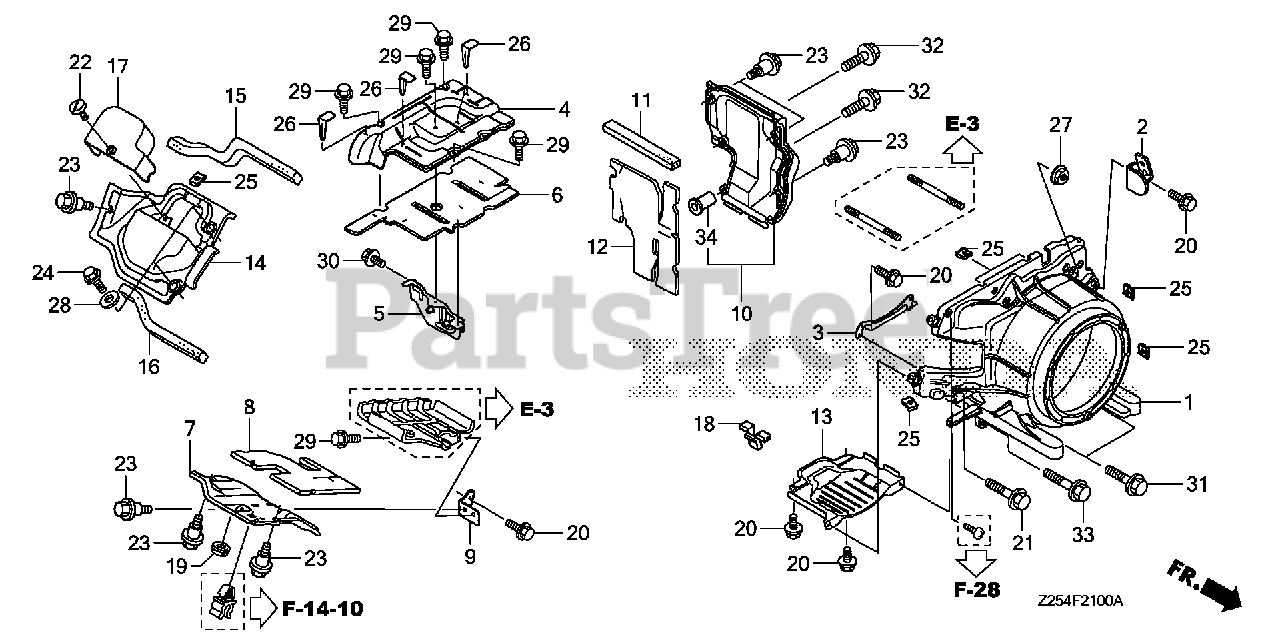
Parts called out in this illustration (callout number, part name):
1	COVER, FAN
2	PLATE, R. SIDE
3	BRACKET, FAN COVER
4	SHROUD (UPPER)
5	BRACKET, SHROUD (UPPER)
6	INSULATOR, SHROUD (UPPER)
7	SHROUD (LOWER)
8	INSULATOR, SHROUD (LOWER)
9	BRACKET, SHROUD (LOWER)
10	SHROUD, R. SIDE
11	SEAL, R. SIDE COVER
12	INSULATOR, R. SIDE COVER
13	SHROUD (LOWER)
14	SHROUD, HEAD COVER
15	SEAL, HEAD COVER SHROUD (UPPER)
16	SEAL, HEAD COVER SHROUD (LOWER)
17	COVER, PLUG
18	RUBBER, OIL CHECK
19	GROMMET, SPEAKER PANEL
20	BOLT, FLANGE (6X12) (CT200)
21	BOLT, FLANGE (6X23)
22	BOLT, AIR CLEANER COVER (- SCREW)
22	SCREW, SPECIAL (6X16)
23	BOLT, SPECIAL (6MM)
24	BOLT, FLANGE (6X12) (CT200)
25	NUT, SPRING (6MM)
26	CLIP, INSULATOR BIND (A)
27	NUT, FLANGE (6MM)
28	WASHER, PLAIN (6MM)
29	BOLT, FLANGE (6X12) Use up to Engine SN 1543277.
30	BOLT, FLANGE (6X12)
31	BOLT, FLANGE (6X20)
32	BOLT, FLANGE (6X22)
33	BOLT, FLANGE (6X30)
34	COLLAR, FAN COVER (Honda Code 5580527). (N/A: SEE ASSEMBLY)
